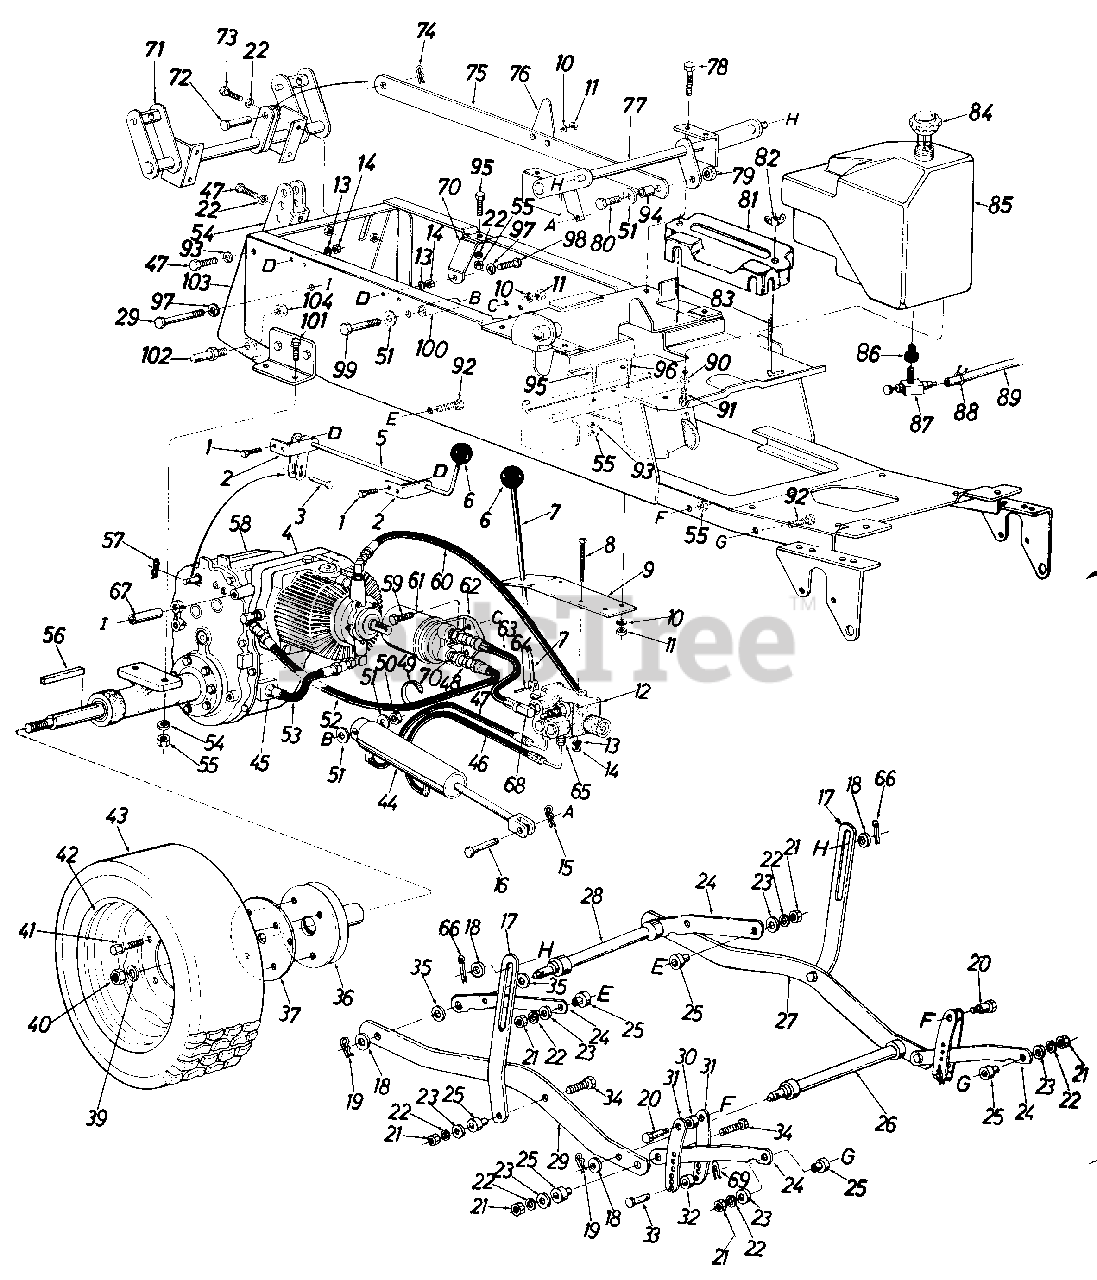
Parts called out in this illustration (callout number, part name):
1	Hex Bolt 1/4-20 x .75" Lg.
4	Hydrostatic Pump Comp.
5	Hi-Lo Control Handle Ass'y.
6	Ball Knob
7	Cylinder Control Handle Ass'y.
8	Truss Mach. Scr. 1/4-20 x 3.00" Lg.
11	Hex Nut 5/16-18 Thd.
12	Valve Ass'y. Comp.
13	L-Wash. 1/4" I.D.
14	Hex Nut 1/4-20 Thd.
15	Hairpin Cotter 1/2" Dia.
16	Clevis Pin 1/2" Dia.
19	Hairpin Cotter
20	Shld. Bolt .498 Dia. x .66
21	Hex Nut 3/8-24 Thd.
22	L-Wash. 3/8" I.D. H.D.
23	Fl-Wash. .38 I.D. x 1.00"
26	Cross Shaft Ass'y. Front
29	Hex Bolt 1/2-13 x 2.75"
30	Collar .50" I.D. x 1.0"
33	Clevis Pin 3/8" Dia.
34	Hex Bolt 3/8-24 x 1.50" Lg. Grade 5
35	Fl-Wash. .62" I.D. x 1.25"
39	L-Wash. 3/4" I.D.
40	Hex Ins. L-Nut 3/4-16 Thd.
41	Wheel Lug Bolt
44	Hydraulic Cylinder
45	7/8-14 UNF-2A Thd. 5/8 Tube Fitting
46	Valve to Cylinder Hose 20"
47	Hex Bolt 3/8-16 x .75" Lg. Grade 5
48	Bushing Reducer 1/2-14 NPTF to 3/8-18 NPTF
49	Cable Tie
50	Hex Jam Nut 1/2-20 Thd.
51	Fl-Wash. .50" I.D. x 1.25
52	Filter Return Hose 24" Lg.
53	Pump Tube Ass'y.
55	Hex Nut 3/8-16 Thd.
56	Sq. Key 1/4" x 1/4" x 2"
57	Hairpin CoKer 1/4" Dia.
58	Peerless Transaxle
59	Hex Bolt 5/16-18 x 1.25"
60	Pump to Valve Hose
61	Fram Filter Ass'y. PH-16
62	Filter Base
63	Valve to Filter Hose 8.38"
64	Spring Pin Spiral 1/8" Dia.
65	Flare Adapter
66	Cotter Pin 1/8" Dia. x 1.0
67	Spacer
68	Adapter 9/16-18 to 9/16-18
69	Hairpin Cotter
70	Transmission Brace
73	Hex Scr. 3/8-16 x 1.00" Lg. Grade 5
74	Cotter Pin 1/8" Dia. x 1.25
79	Hex Cent. L-Nut 1/2-20 Thd
80	Hex Scr. 1/2-20 x 1.25" Lg.
81	Battery Cover
82	Wing Nut 1/4-20 Thd.
83	Battery Hold Down Rods
84	Gas Tank Cap
85	Gas Tank Ass'y.
86	Bushing
87	Fuel Shut-Off Valve with Screen
88	Hose Clamp
89	Gas Line 23" Lg.
90	Bell-Wash.
91	Hex Scr. 1/4-20 x 38" Lg.
92	Hex Scr. 3/8-24 x 1.50" Lg.
93	L-Wash. 3/8" Scr.
94	Push Bar Sleeve
95	Hex Scr. 3/8-16 x 1.00 Lg. Grade 5
96	Hex Scr. 5/16-18 x 75" Lg.
97	L-Wash. 1/2" Scr.
98	Hex Scr. 1/2-13 x 1.25" Lg.
99	Hex Scr. 1/2-20 x 31/2" Lg. Grade 5
100	Spacer for Cylinder
101	Hex Scr. 3/8-16 x 1 75" Lg.
102	Link Clevis Pin
13196-0648	PLATE-HITCH - TECH GRAY (0648)
13196-0665	PLATE-HITCH - YARDMAN GREEN (0665)
